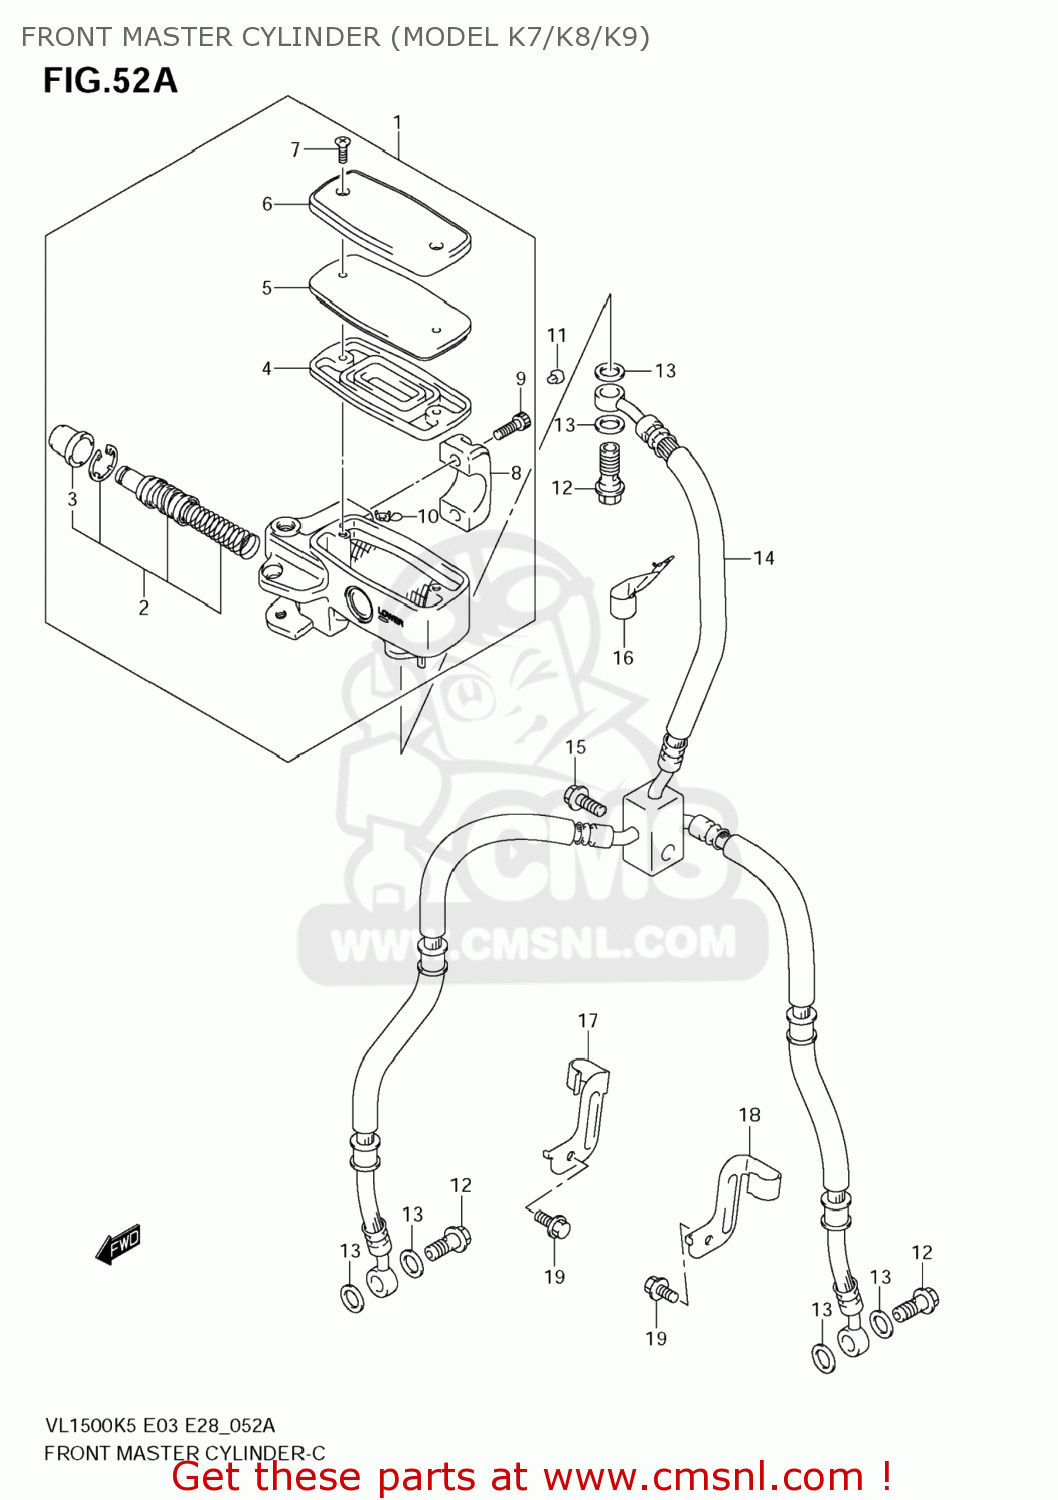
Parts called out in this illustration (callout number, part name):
1	CYLINDER ASSY,FR MASTER
2	PISTON/CUP SET
3	BOOT
4	DIAPHRAGM
5	PLATE,DIAPHRAGM
6	CAP
7	SCREW
8	HOLDER
9	BOLT
10	PROTECTOR
11	CAP(OD:10)
12	BOLT UNION
13	WASHER(10X15X1.5)
14	HOSE,RR BRAKE
15	BOLT(6X25)
16	CLAMP,FR BRAKE HOSE
17	CLAMP,FR BRAKE HOSE,R
18	CLAMP,FR BRAKE HOSE,L
19	BOLT(6X12)
